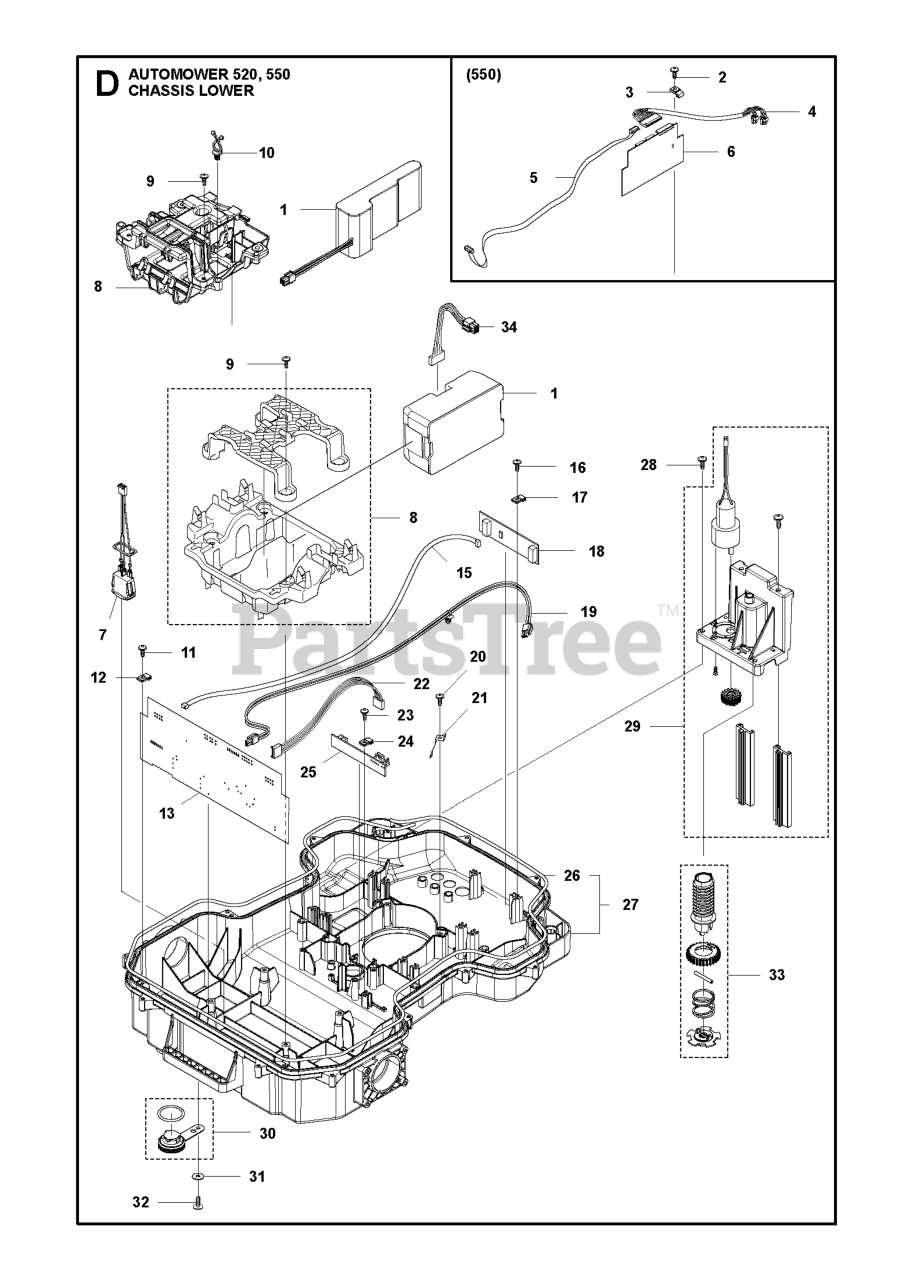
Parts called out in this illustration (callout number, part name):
1	BATTERY
1	BATTERY LI-ION
2	SCREW 14MM
3	CLAMP PCB
4	LOOM ULTRA SONIC EXTENSION
5	LOOM AUX
6	PRINTED CIRCUIT ASSY ULTRASONI
7	LOOM ON/ OFF
8	HOLDER KIT BATTERY
8	HOLDER BATTERY
9	SCREW ITXPANT
10	HOLDER TWIST LOCK
11	SCREW 14MM
12	CLAMP PCB
13	PRINTED CIRCUIT ASSY PCBA MAIN
15	LOOM LOOP SENSOR
16	SCREW 14MM
17	CLAMP PCB
18	PRINTED CIRCUIT ASSY LOOP SENS
19	LOOM CHARGING LINK HIGH CHARGI
20	SCREW 14MM
21	SPRING GUIDE HEIGHT ADJUSTMENT
22	LOOM HEIGHT ADJUSTMENT
23	SCREW 14MM
24	CLAMP PCB
25	PRINTED CIRCUIT ASSY PCBA CUTT
26	SEALING STRIP
27	CHASSIS KIT LOWER
28	SCREW 14MM
29	MOTOR ASSY HEIGHT MOTOR
30	PLUG KIT
31	WASHER
32	SCREW ITXPANT
33	SCREW KIT
34	WIRING ASSY BATTERY CABLE
